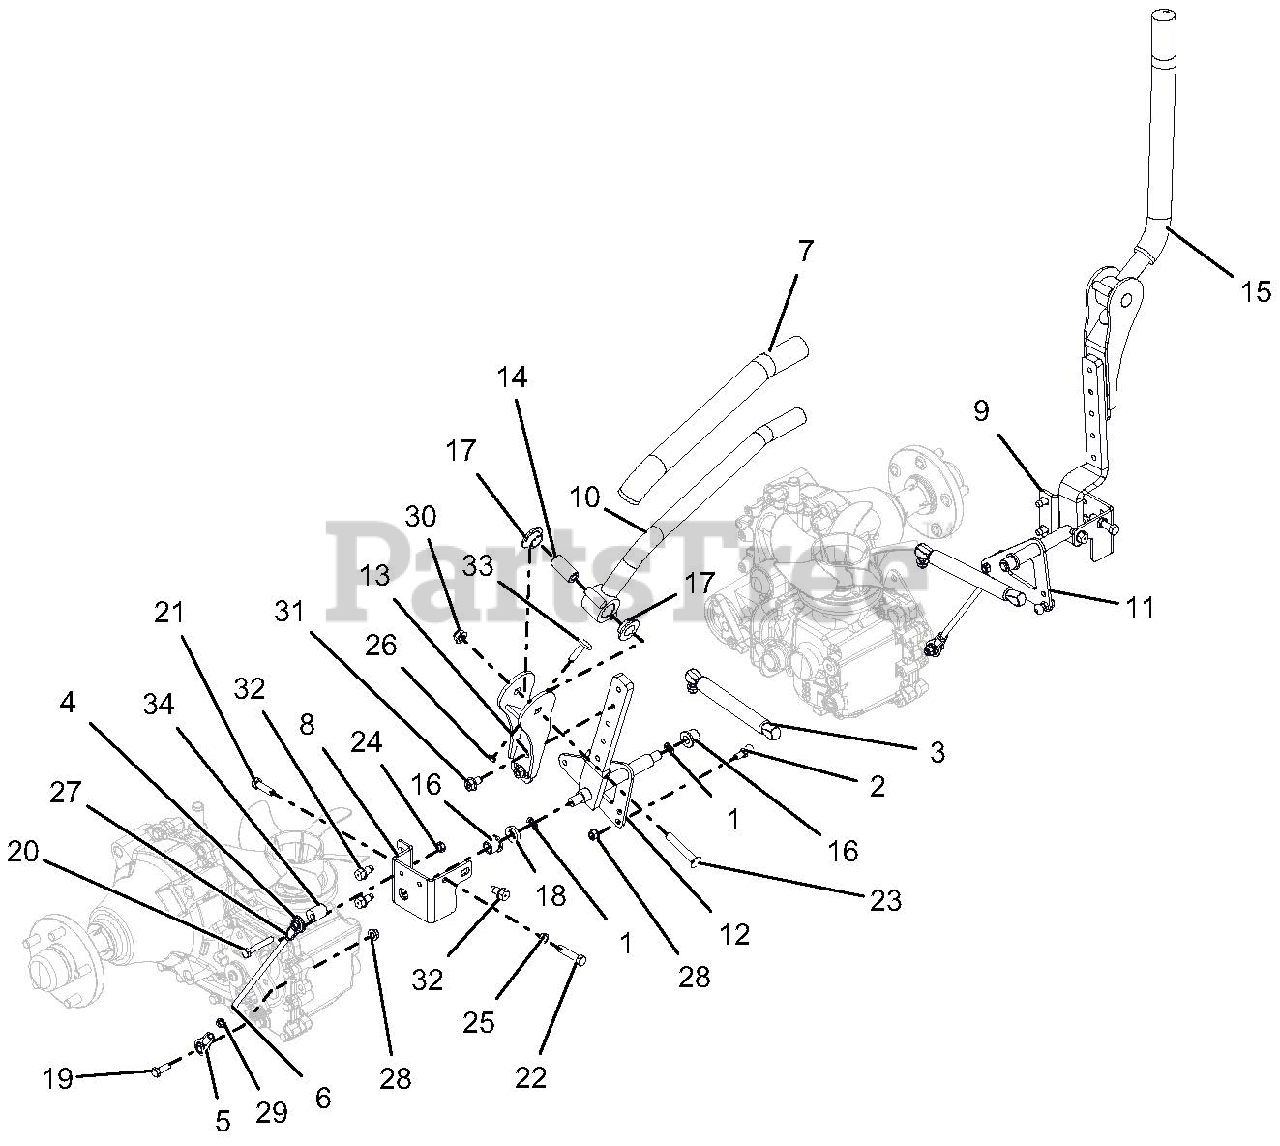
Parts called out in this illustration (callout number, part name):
1	WAVE WASHER .531X.781X.125 FH
2	STUD-BALL
3	DAMPER,
4	ALIGNABALL, 5/16 RH THREAD
5	ALIGNABALL, 5/16 LH THREAD
6	ROD, STEERING
7	GRIP, HANDLEBAR
8	BRKT, RH CONTROL ARM STOP
9	BRKT, LH CONTROL ARM STOP
10	WLDMT, RH STEERING ARM
11	WLDMT, LH LOWER CONTROL ARM
12	WLDMT, RH LOWER CONTROL ARM
13	MOUNT, STEERING ARM, ADJUSTABLE
14	SPCR, STEERING ARM
15	WLDMT, LH STEERING ARM
16	BHSG-FLG .500X.750X.750X.125
17	BSHG, FLANGE .762 X 1.48 X .44 NYLON
19	BLT-HEX .31-18X1.00 GR5 YWZC
20	BLT-HEX .31-18X2.00 GR5 YWZC
21	BLT-HEX .38-16X1.25 GR5 YWZC
22	BLT-HEX .38-16X1.75 GR5 YWZC
23	BLT-RHDSSQNK .38-16X2.50 G5YZ
24	NUT-LK-CTR .31-18 YWZC
25	NUT, JAM .375-16 YWZC
26	NUT, JAM .312-18 YWZC
27	NUT-JAM
28	NUT, LK-TOP-FLG .312-18 YWZC
29	NUT, JAM -LH .31-24 YWZC
30	NUT-LK-NYL-FLG .38-16 YWZC
31	BLT-SERHFWH .38-16X.62 YWZC
32	SCR-TAP .38-16X.75 HWH TR YWZ
33	BUMPER, STUD MOUNTED
34	ECCENTRIC
